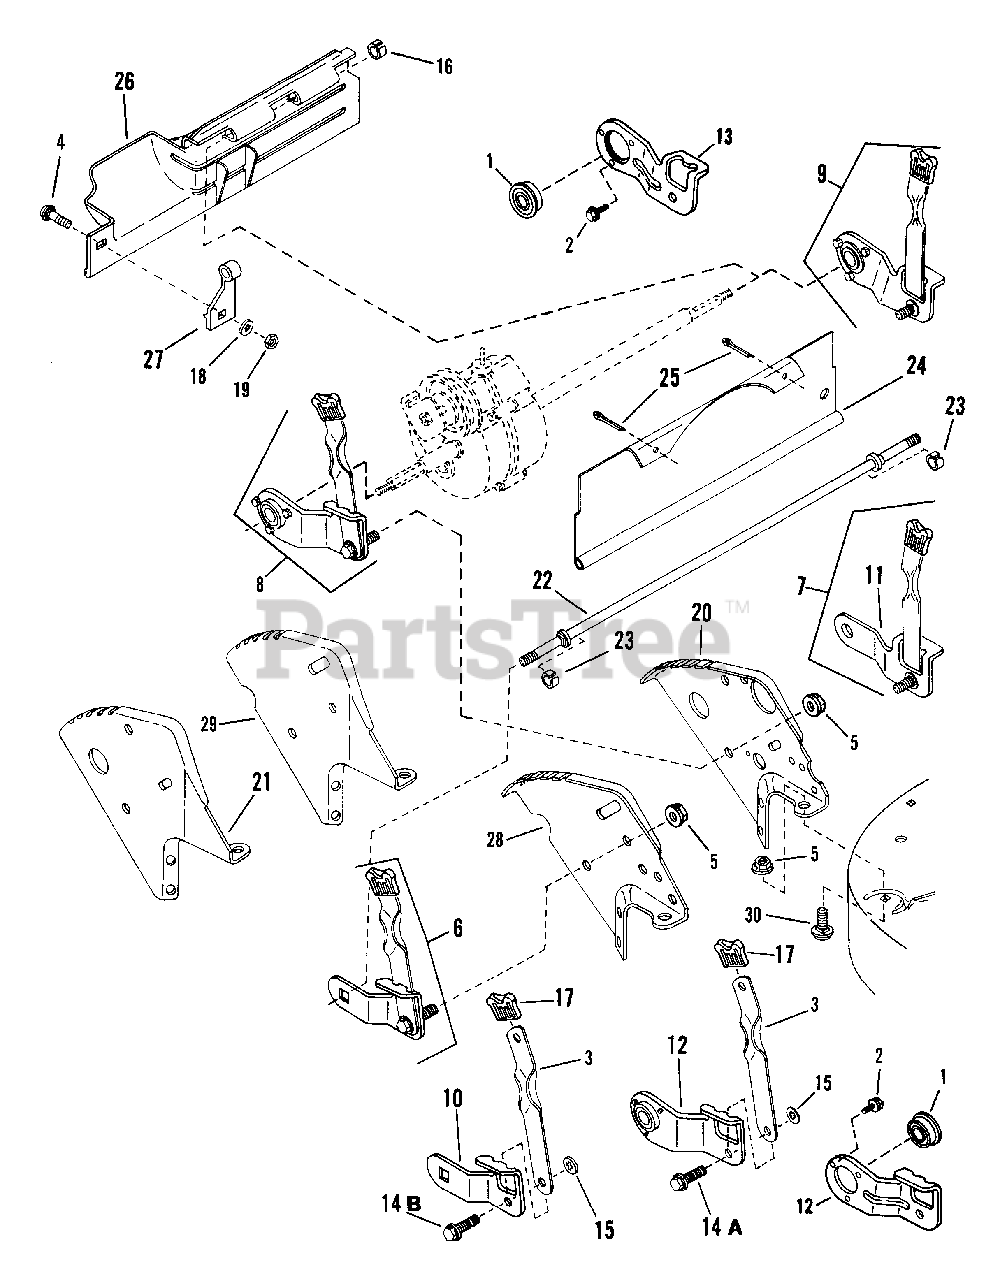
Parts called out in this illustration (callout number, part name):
1	BEARING
2	SCREW, #10-32x3/8" Self-Tapping
3	LATCH, Height Adjusting
4	BOLT, 1/4-20 x 1/2" Short Neck Carriage (Gr. 5)
5	NUT, 5/16-18 Hex Flange Lock
6	ASSEMBLY, Wheel Arm (Square Hole, Front Left & Rear Right)
7	ASSEMBLY, Wheel Arm (Round Hole, Front Right & Rear Left)
8	ASSEMBLY, Wheel Arm (Rear Right "P" Models)
9	ASSEMBLY, Wheel Arm (Rear Left "P" Models)
10	ARM, (Square Axle End)
11	ARM, (Round Axle End)
12	ARM, Wheel Rear Right "P" Models
13	ARM, Wheel Rear Left "P" Models
14A	BOLT, 5/16-18 x 1" Shoulder (Self-Propelled "P" Models)
14B	BOLT, 5/16-18 x 3/4" Shoulder (Push Models)
15	RETAINER, 5/16 Bolt
16	RING
17	GRIP, Latch
18	WASHER, 1/4 Internal Tooth Lock
19	NUT, 1/4-20 Hex
20	BRACKET, Right Rear Wheel (Self-Propelled "P" Models)
21	BRACKET, Left Rear Wheel (Self-Propelled "P" Models)
22	AXLE, (Rear - Push Models, also front axle on all models)
23	RING (Push Models)
24	GUARD, Rear Foot
25	PIN, 1/8x1-1/2" Cotter
26	GUARD, Rear Foot (Self-Propelled "P" models)
27	SUPPORT, Foot Guard
28	BRACKET, Right Rear Wheel (Push Models)
29	BRACKET, Left Rear Wheel (Push Models)
30	BOLT, 5/16-18 x 3/4" Short Neck Carriage
